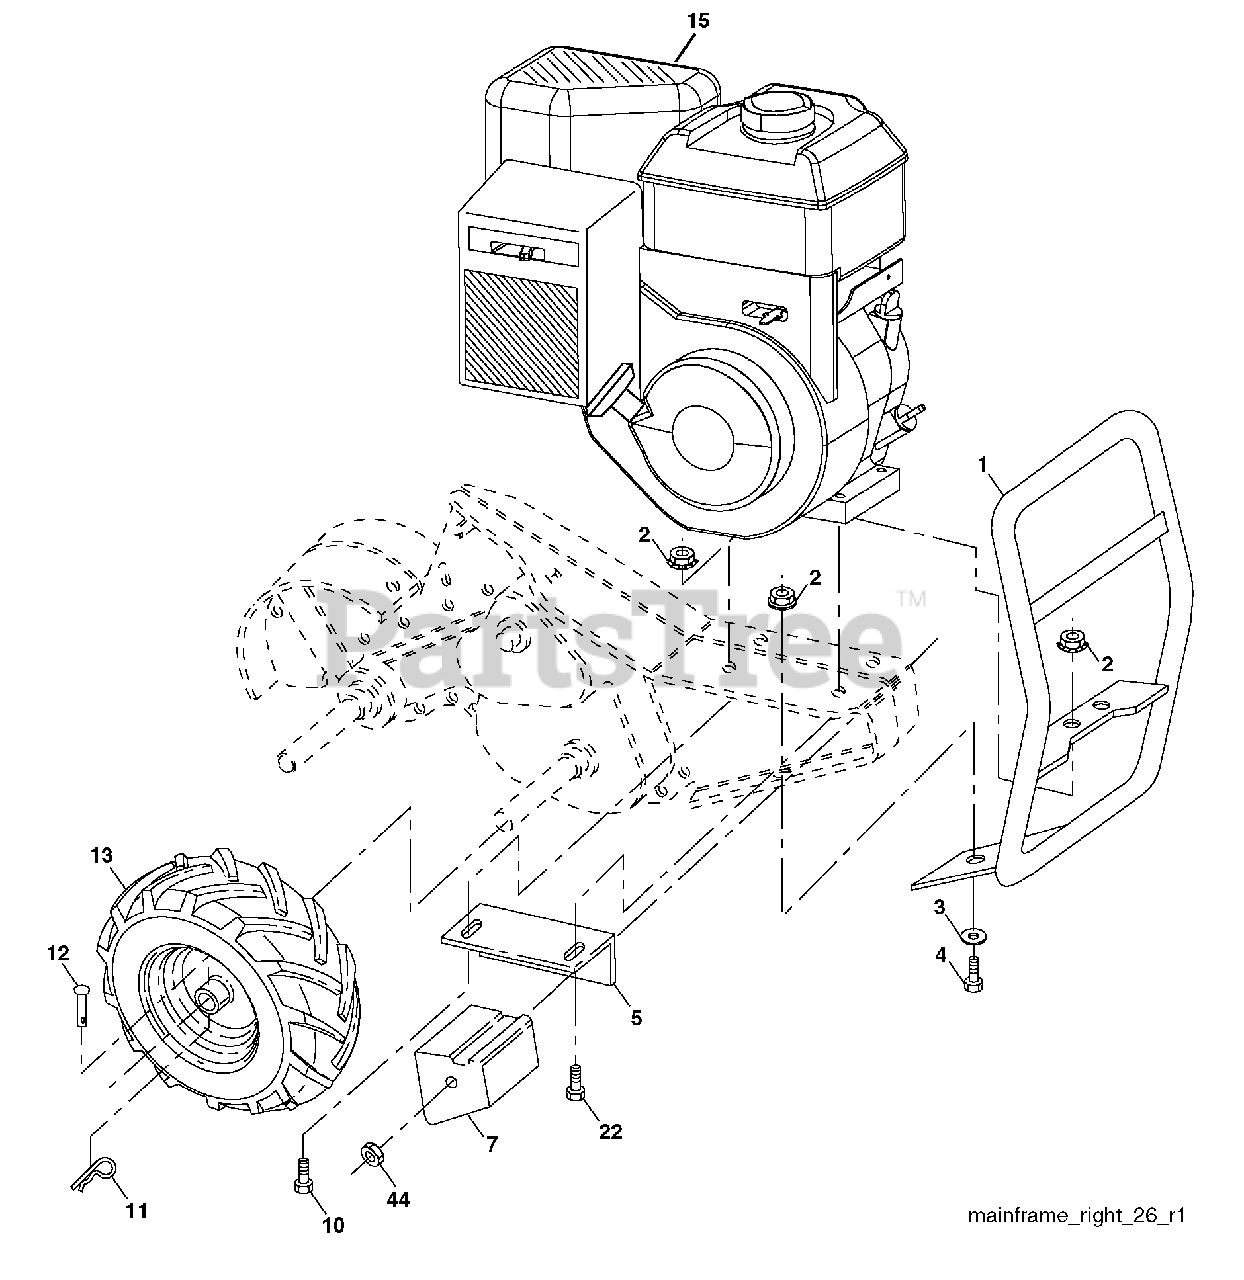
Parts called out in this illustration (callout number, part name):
1	BumperAsm.
2	Locknut,Hex,Flange5/1618
3	Washer11/32x11/16x16Ga.
4	Bolt5/1618x3/4
5	Bracket,ReinforcementR.H.
6	Bolt5/1618x13/4
7	CounterWeight,R.H.
10	Bolt,Hex5/1618x11/2
11	Clip,Hairpin
12	Rivet,Drilled
44	NutKepsHex3/816unc
